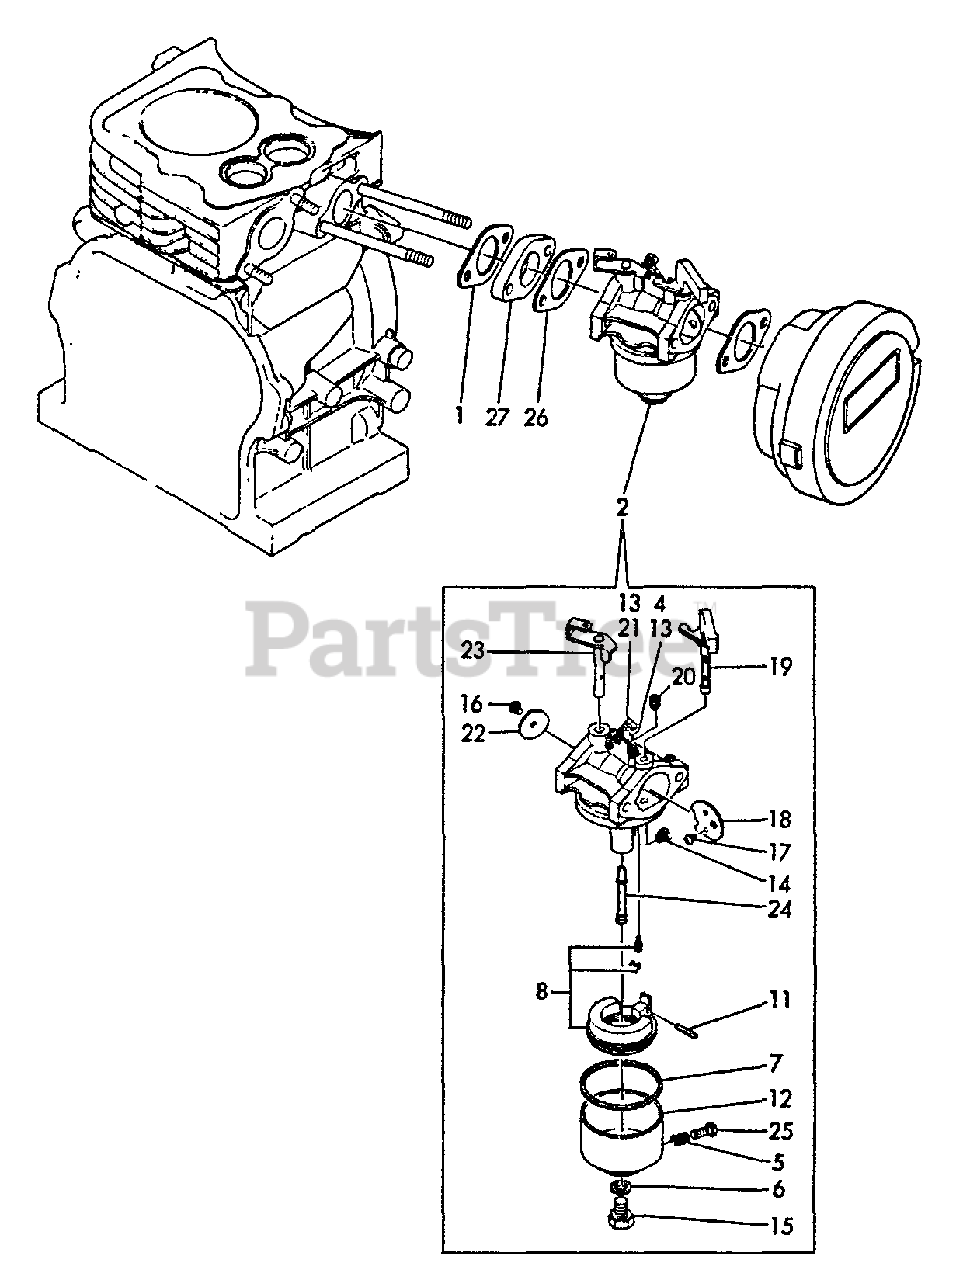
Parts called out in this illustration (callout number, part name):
1	GASKET, EXHAUST
2	CARBURETOR
4	SCREW, THROTTLE
6	WASHER
7	GASKET
8	NEEDLE ASSY
11	PIN
12	BODY, FLOAT CHAMBER
14	JET, MAIN
15	BOLT
16	SCREW
17	SCREW -- TAPPING
18	VALVE, CHOKE
19	SHAFT, CHOKE
20	JET, PILOT
21	SCREW
22	VALVE, THROTTLE
23	SHAFT, THROTTLE
24	NOZZLE, MAIN
25	SCREW
26	GASKET, INTAKE
27	INSULATOR, INTAKE
